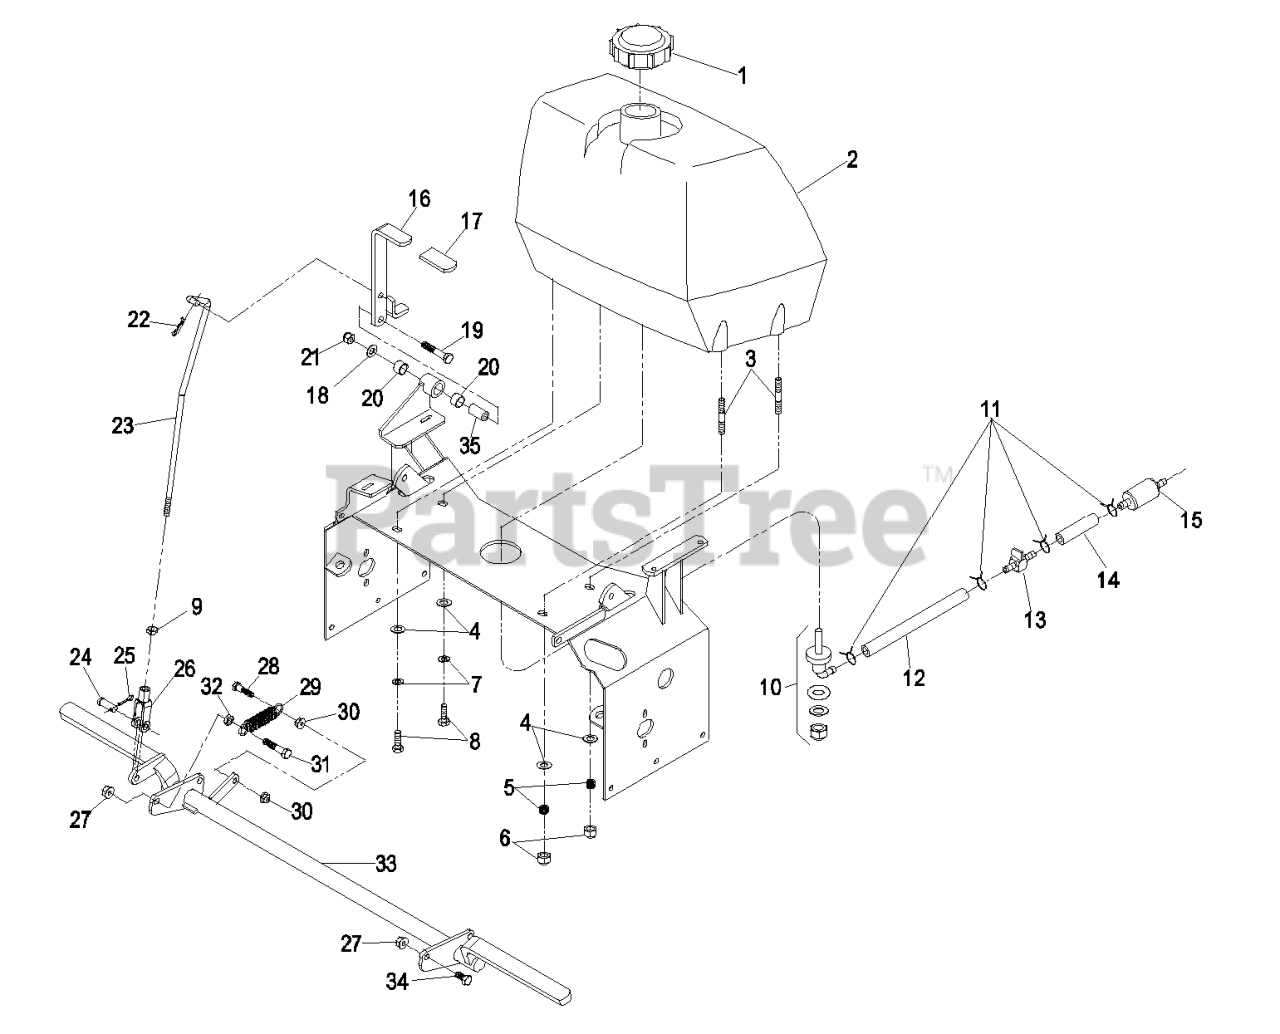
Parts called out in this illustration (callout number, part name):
1	CAP-FUEL, GAS
2	ASM,FUEL TANK W/B
3	STUD
4	WASHER-PLAIN
5	SPRING-TANK, FUEL
6	NUT-LOCK, NI
7	WASHER-LOCK
8	SCREW-HH
9	NUT-HJ
10	FITTING-FUEL, BULKHEAD
12	HOSE-FUEL
13	VALVE-FUEL
14	HOSE-FUEL
15	Kawasaki Part No. 49019-7001 Fuel Filter
16	LEVER,PRK BRK W/DECALS
17	GRIP-LEVER
18	WASHER-FLAT
19	SCREW-HH
20	SLEEVE-BUSHING
21	NUT-LOCK, NI
22	PIN-COTTER
23	LINKAGE, PARK BRAKE
24	PIN-CLEVIS
25	PIN-COTTER
26	YOKE-LINKAGE, BRAKE
27	NUT-HHF, WHIZ
28	SCREW-HH
29	SPRING-IDLER
31	SCREW-HH
32	NUT-JAM
34	SCREW-HH
35	BUSHING-PIVOT
